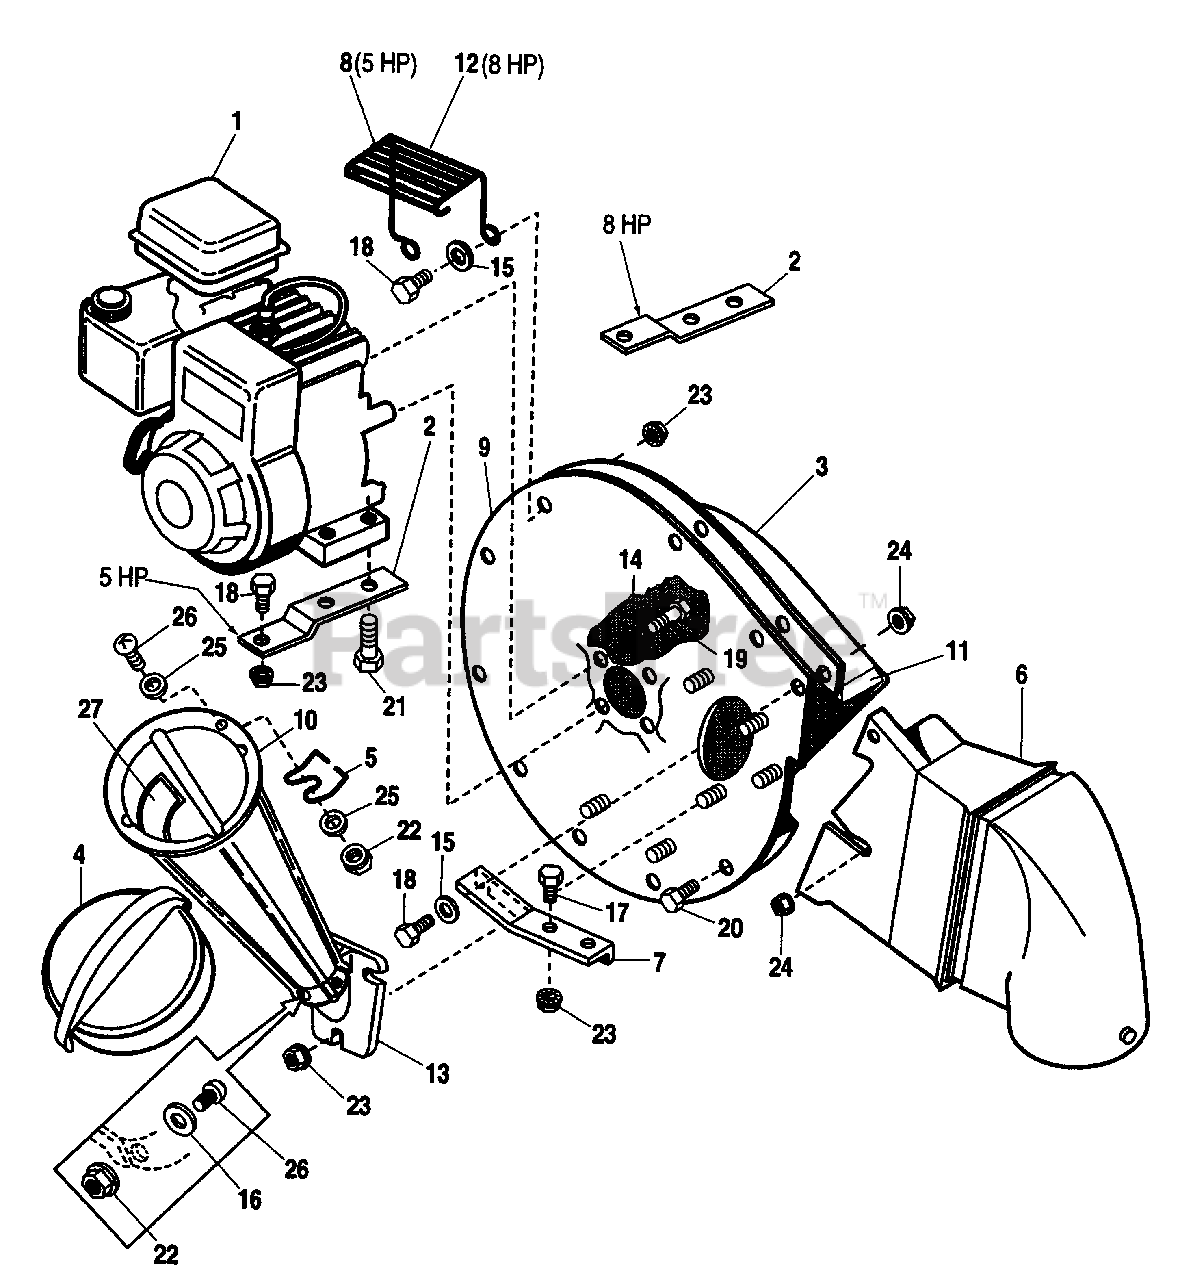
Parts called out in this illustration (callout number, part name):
1	ENGINE, 5 HP (Briggs & Stratton)
1	ENGINE, 8 HP (Briggs & Stratton)
1	ENGINE, 8 HP, Electric Start, (Briggs & Stratton)
2	ENGINE SUPPORT, 5 HP
2	ENGINE SUPPORT, 8 HP
3	FAN HOUSING ASSY.
6	TUBE, Discharge
8	GUARD, Muffler (5 HP models)
9	PLATE ASSY., Engine
10	CONE, Orange
10	CONE, Yellow
11	SEAL, Fan Housing
12	GUARD, Muffler (8 HP models)
13	CASTING, Cone, 3"
14	LOCKWASHER, 5/16
15	WASHER, 5/16
16	WASHER, 1/4
17	CAPSCREW, Hex Hd., 5/16-18 x 3/4
18	CAPSCREW, Hex Hd., 5/16-18 x 1
19	CAPSCREW, Hex Hd., 5/16-24 x 3/4
20	CAPSCREW, Hex Hd., 5/16-18 x 3/4
21	SCREW, Taptite, 3/8-16 x 1-1/4 (Manual start models only)
22	NUT, 2 Way Lock, 1/4 x 20
23	NUT, Serrated, Flange Lock., 5/16-18
24	NUT, Hex, Flange Lock, 5/16-18
25	WASHER, 1/4
26	SCREW, Allen Hd. 1/4 x 3/4
27	DECAL, Danger
